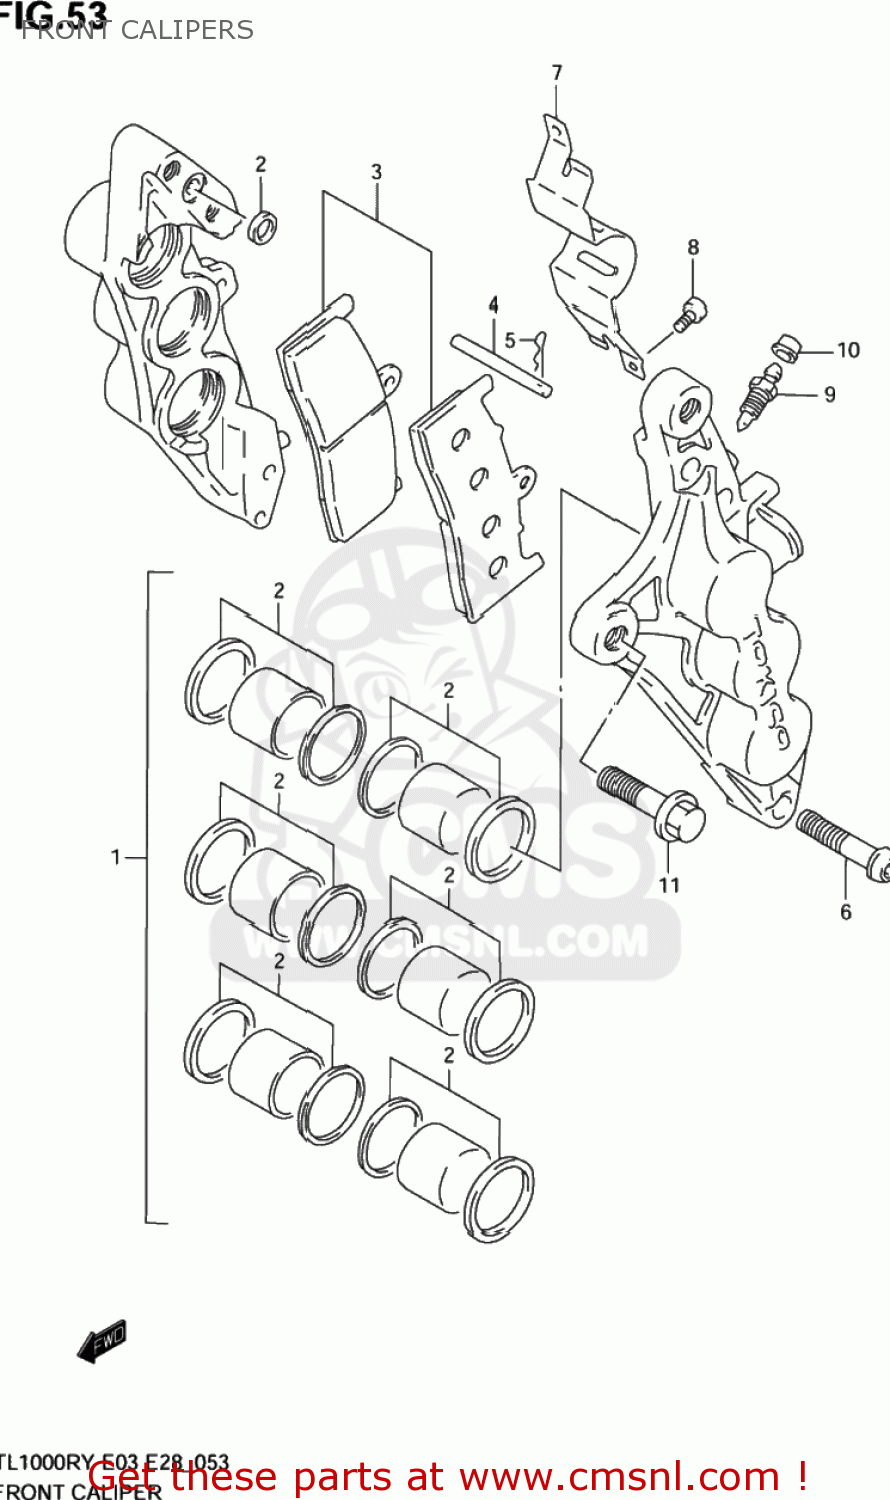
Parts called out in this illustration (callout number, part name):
1	PISTON SET
2	SEAL SET,PISTON
3	PAD SET (NAS)
4	PIN,PAD
5	CLIP,PAD PIN
6	BOLT,HOUSING
7	COVER,CALIPER
8	SCREW
9	BLEEDER
10	CAP,BLEEDER PLUG
11	BOLT(10X30)
